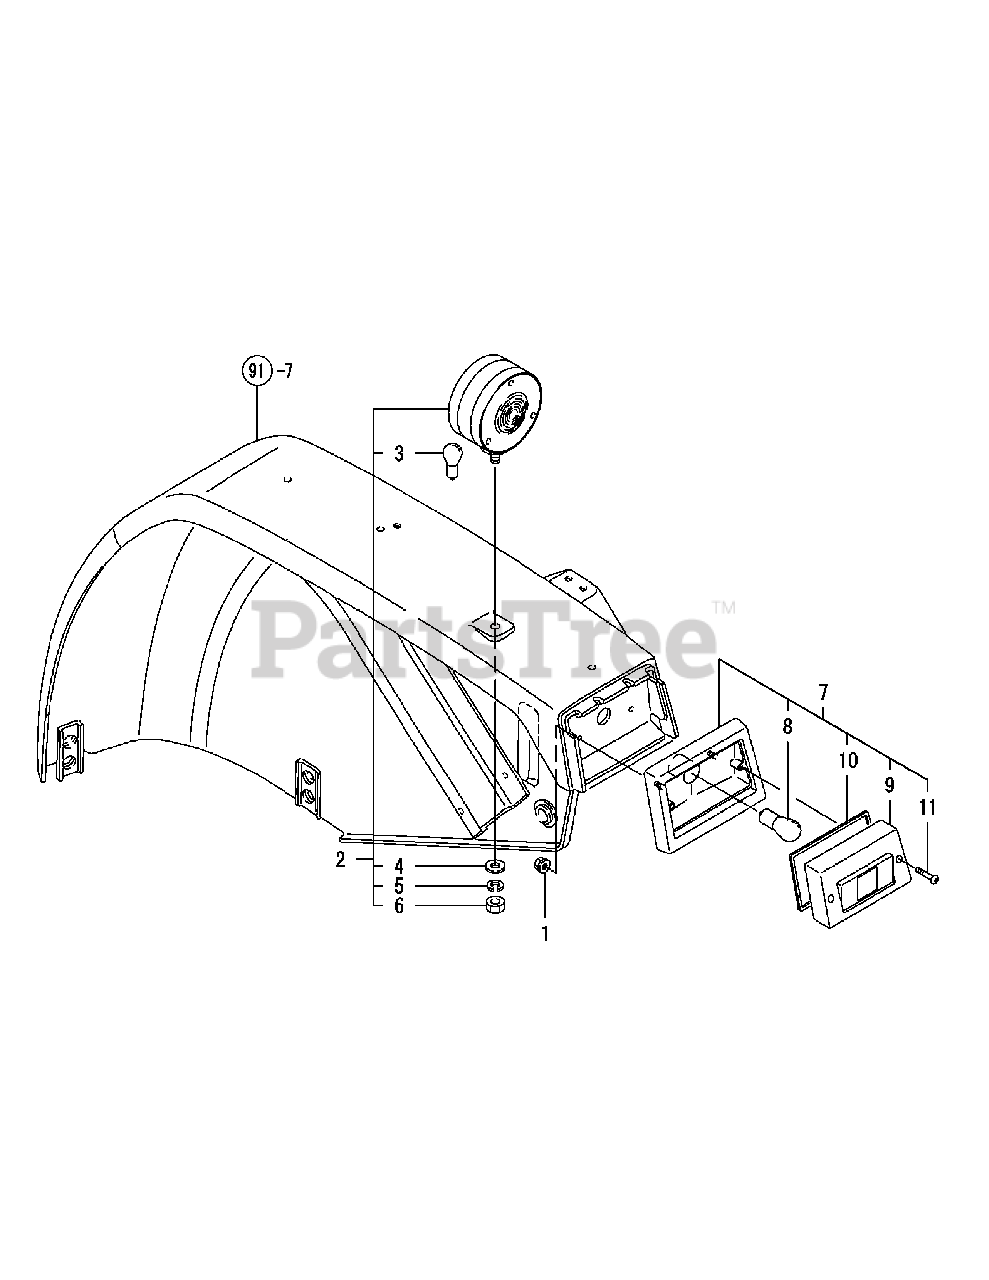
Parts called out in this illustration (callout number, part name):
1	NUT W/WASHER 6
2	LAMP KIT,WARNING
4	WASHER 12,POLISHED
5	SPRING WASHER 12
6	LOCK NUT M12 PLATED
8	BULB 12V-21/5W
